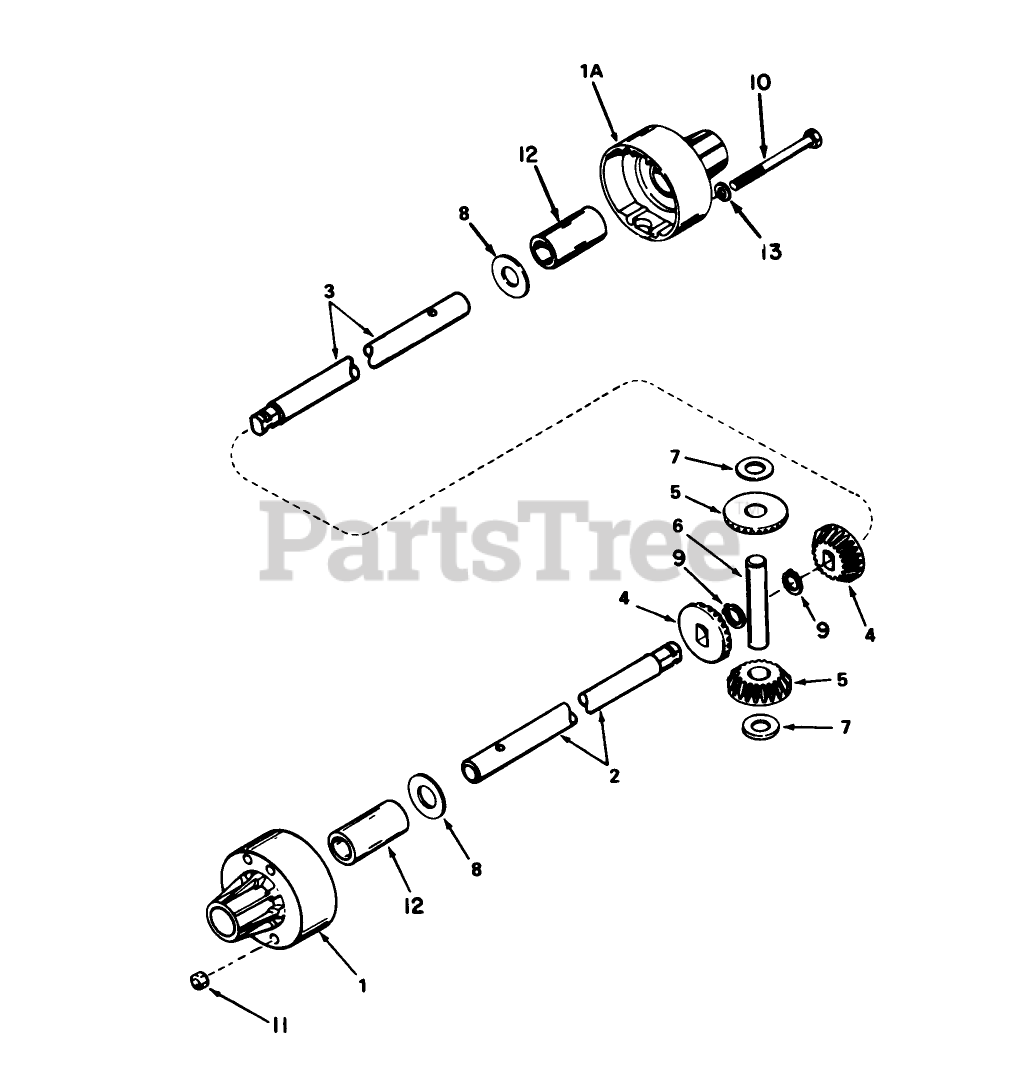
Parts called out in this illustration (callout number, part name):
1	Housing, Differential Carrier (Incl. Ref. #13)
1A	Housing, Differential Carrier (Incl. Ref. #13)
2	Axle(10-1/4" long)
3	Axle (18-7/8" long)
4	Bevel Gear
5	Gear Pinion
6	Pin Drive
7	Washer Thrust
8	Washer
9	Ring-Snap
10	Screw-Hex Hd.
11	Nut-Lock
12	Bushing
13	Washer
